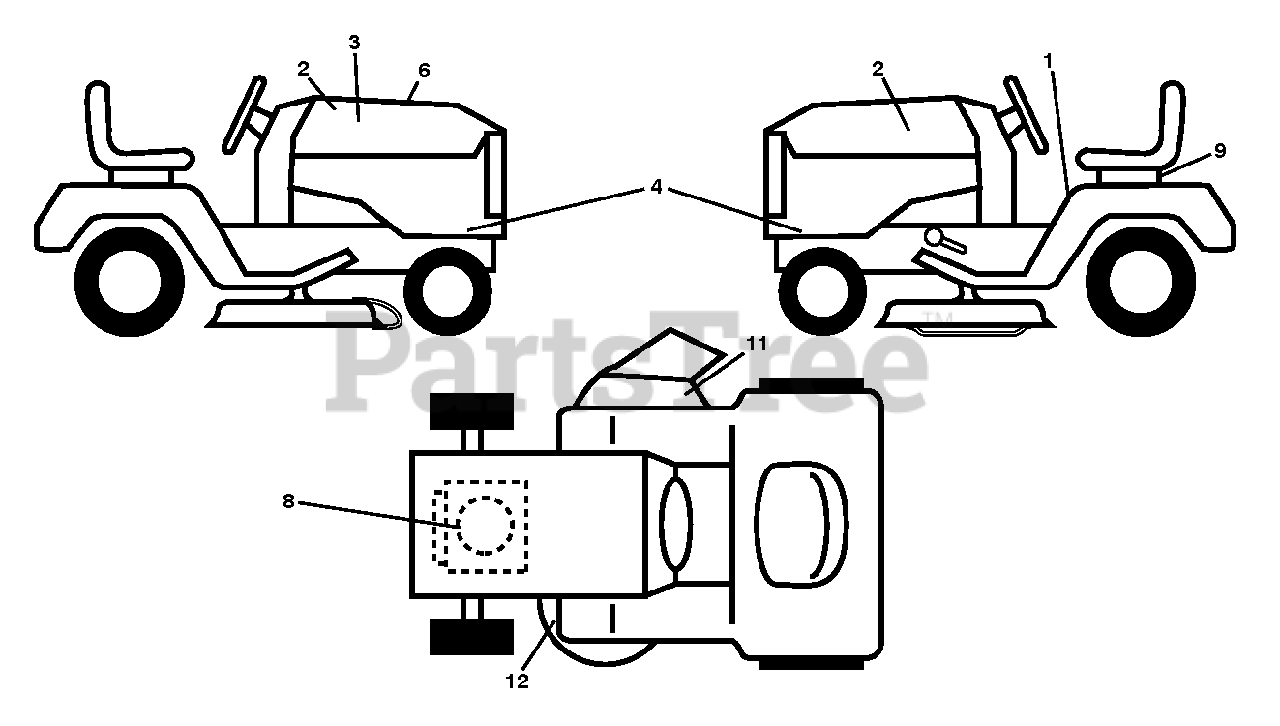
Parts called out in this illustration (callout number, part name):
1	DECAL.FENDER.WARNING.ENGLISH
2	DECAL.BADGE.170MM.TEXTLOGO.
4	DECAL.SIDE.PANEL.LTH2038
6	DECAL.WARNING.CUST.RESP.E85.
8	Decal, Engine BS 20HPXRD
9	DECAL BTRY SYMBOLS
11	DECAL.MOWER.WARN.KEEP.HAND.AWY
12	DECAL.DECK.SCH.36,38,94.NONCR
